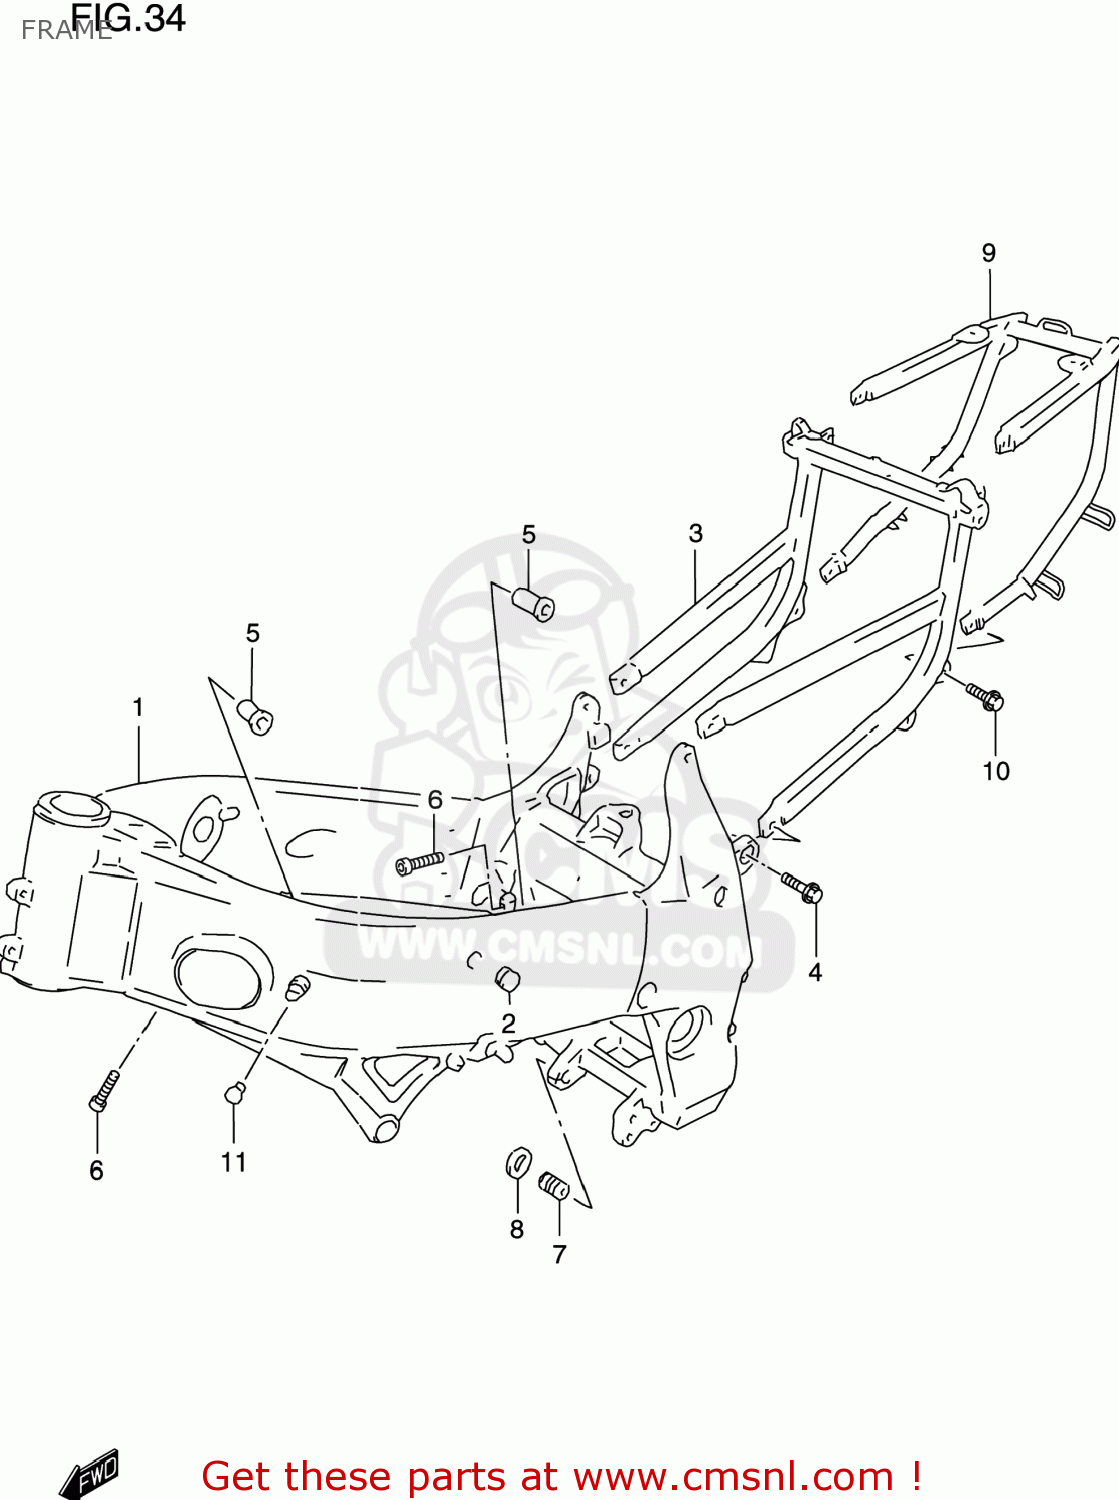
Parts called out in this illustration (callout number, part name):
1	FRAME
2	CAP,TANK RAIL
3	RAIL,SEAT
4	BOLT(10X30)
5	SPACER,ENGINE MOUNTING
6	BOLT
7	BOLT,CRANKCASE ADJUST
8	NUT,CRANKCASE ADJUST
9	GRIP,RR
10	BOLT
11	CAP
